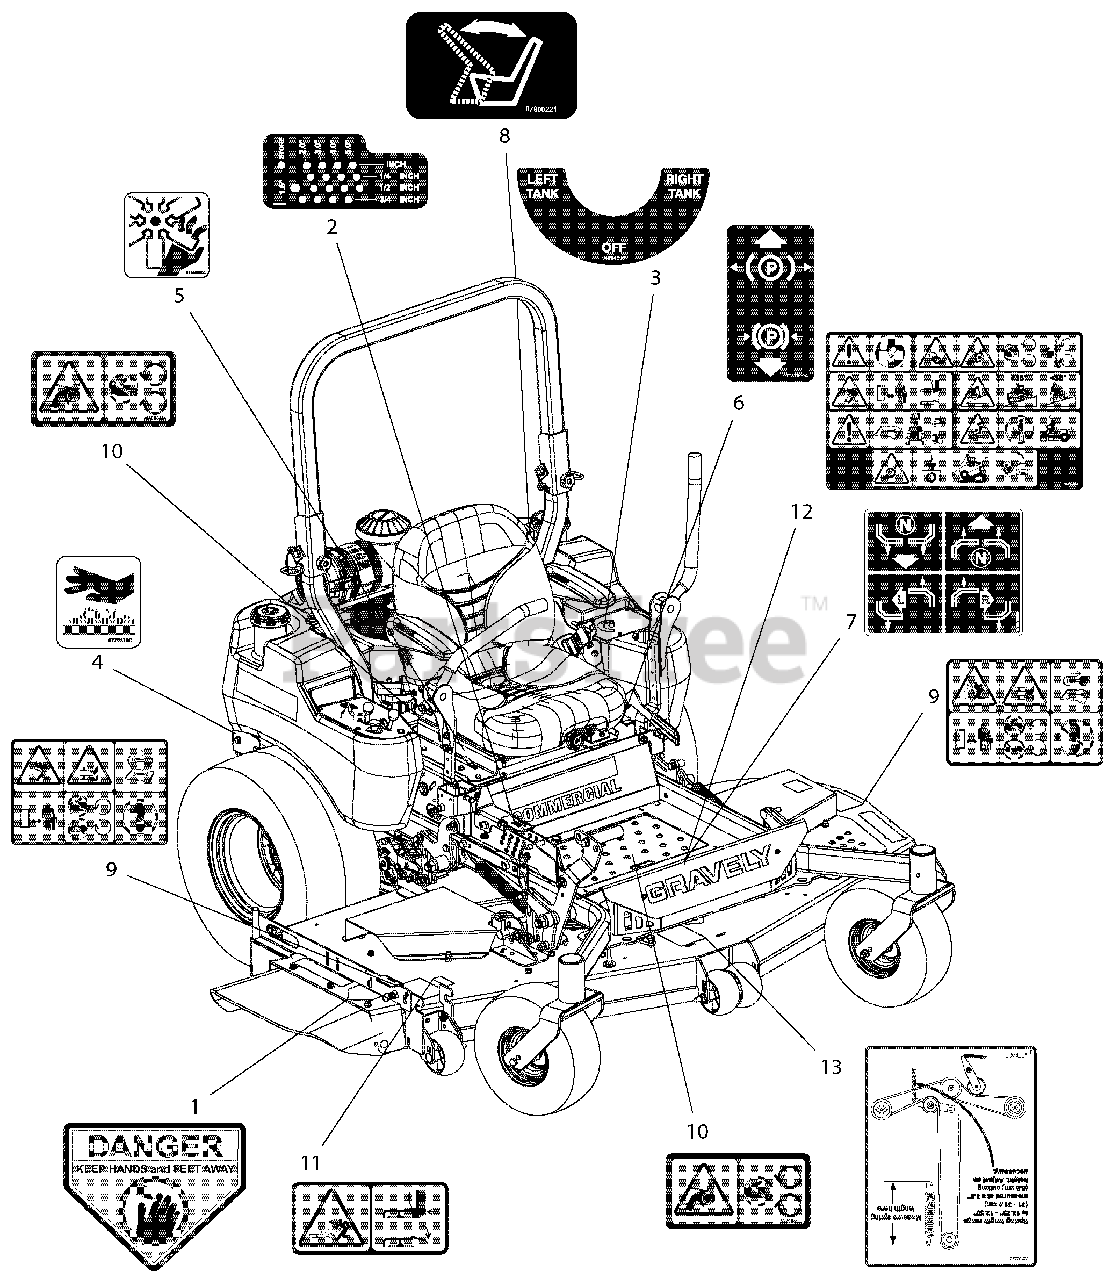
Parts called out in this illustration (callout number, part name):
1	DECAL, DANGER
2	DECAL, HEIGHT OF CUT
3	DECAL, FUEL VALVE
4	DECALHOTSURFACE
5	DECAL, DANGER - FAN
6	DECAL, PARKING BRAKE LEVER
7	DECAL, INSTRUCTIONAL - STEERING
8	DECAL, SEAT RELEASE
9	DECAL, SAFETY - MOWER DECK
10	DECAL, SAFETY - GUARDING
11	DECAL, SAFETY - DECK GUARDING
12	DECAL, MAIN SAFETY, COMMERCIAL
13	DECAL, BELT DIAGRAM 60"
